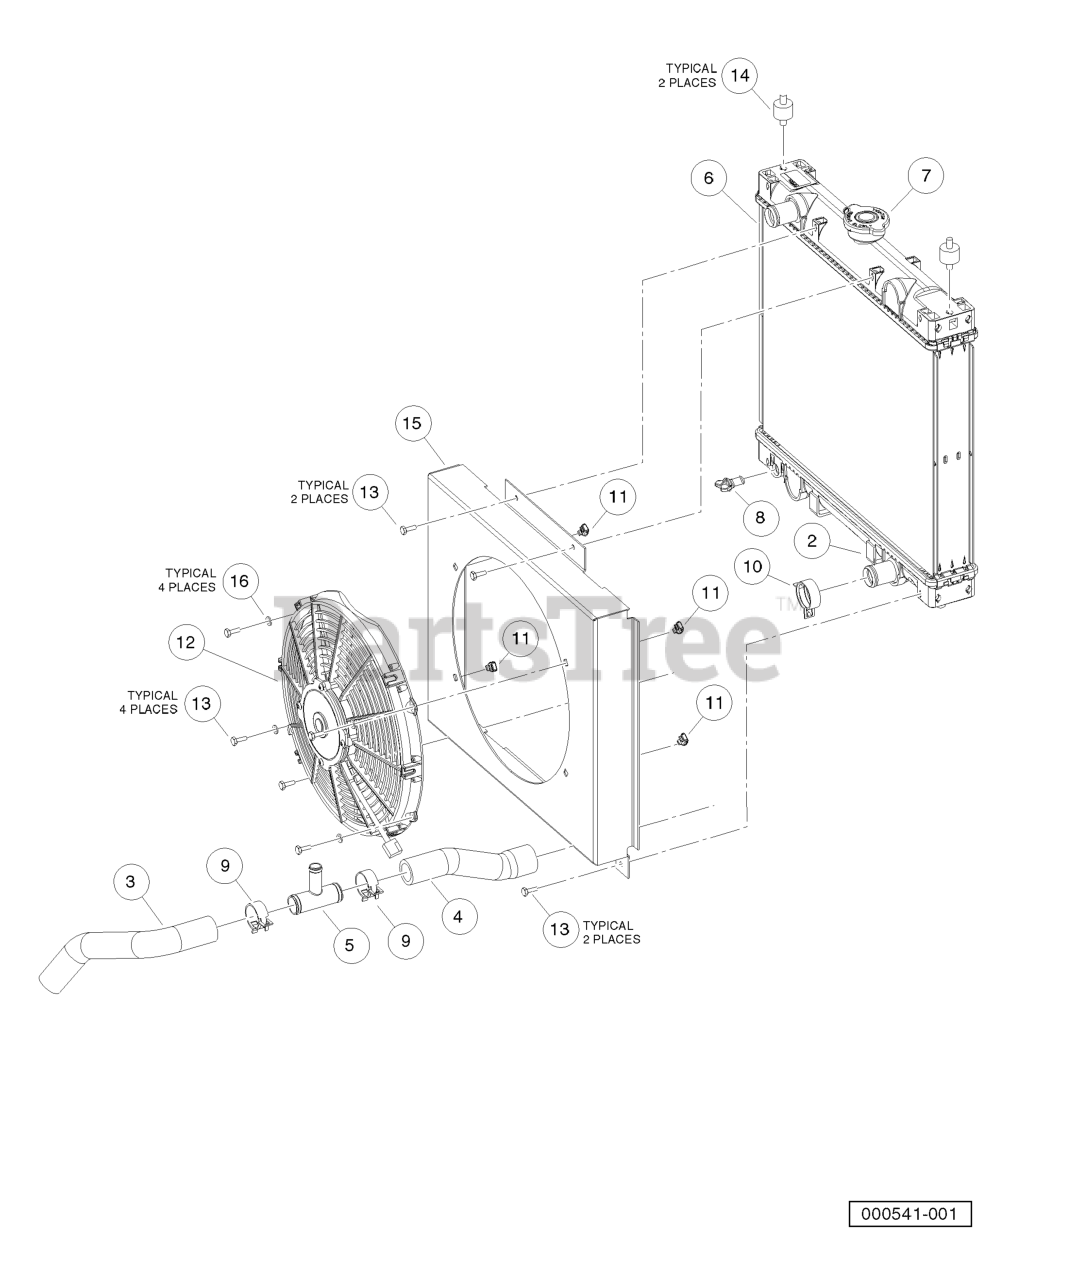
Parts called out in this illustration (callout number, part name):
1	Asm, Radiator
2	BOX INS.BULK
3	HOSE, COOLANT LOWER PIPE
4	HOSE, COOLANT LOWER RAD
5	TEE, COOLANT FILL
6	EXCHANGER, ENGINE COOLANT
7	CAP, RADIATOR, NON PRESSURE
8	DRAIN COCK, RADIATOR
9	CLAMP, HOSE, CTB 35MM
10	CLAMP, HOSE, CTB 38MM
11	NUT, SELF RETAINING
12	FAN, COOLING 12 IN ELECT
13	BOLT, M6 X 1 X 16 LOCTITE
14	ISOLATOR, TWIN STUD, RADIATOR
15	SHROUD, RADIATOR FAN
16	WASHER, M6
